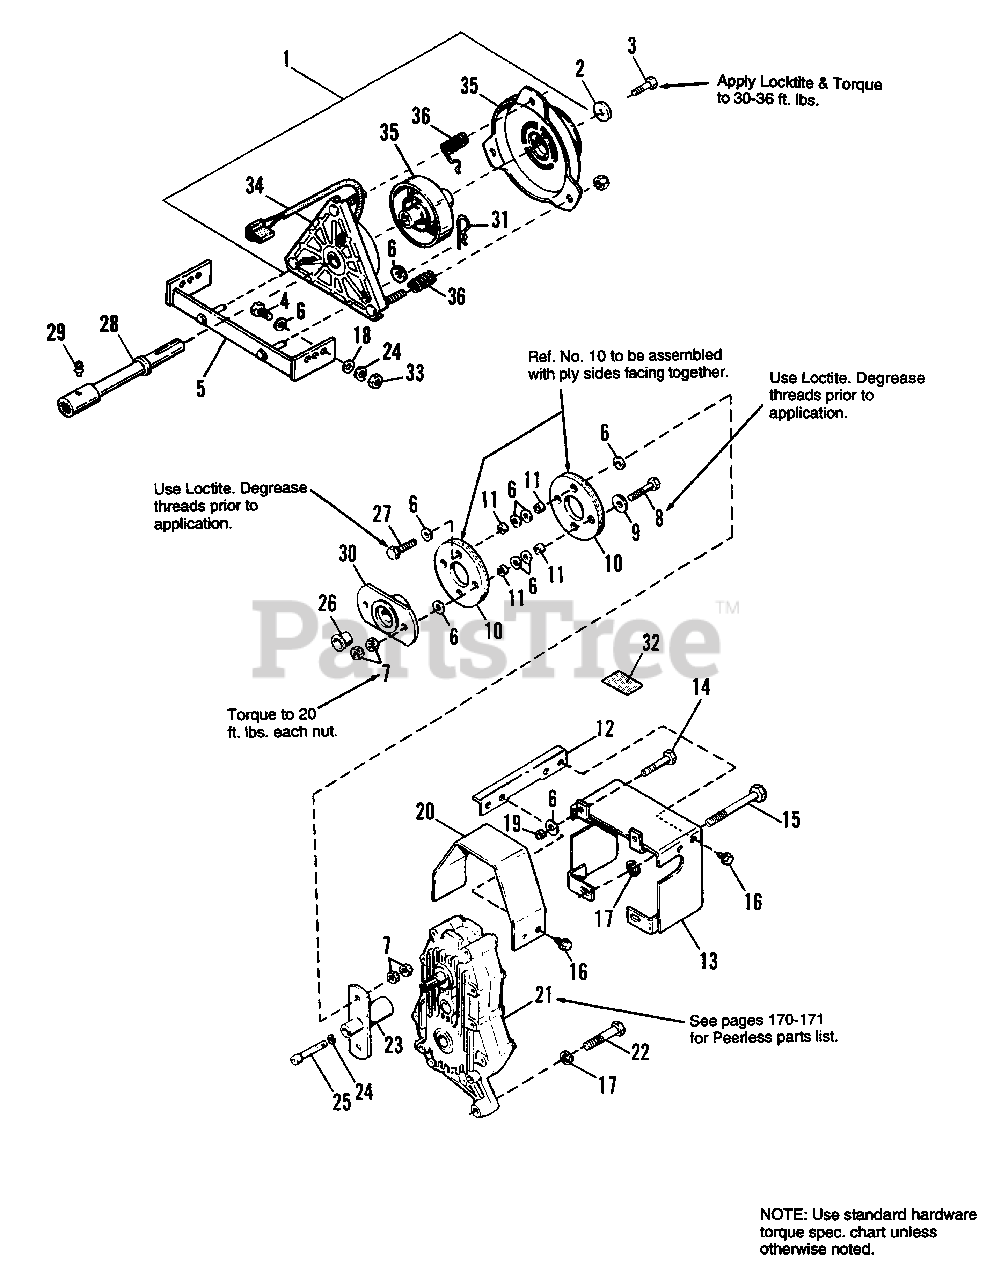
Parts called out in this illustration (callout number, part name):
1	CLUTCH, Electric
3	CAPSCREW, Hex Hd., 3/8-16 x 1, Gr. 5
4	CAPSCREW, Whizlock, 5/16-18 x 1
5	PLATE ASSY., Rear P.T.O.
6	WASHER, Plain, 11/32 I.D. X 3/4 O.D. X 1/16
7	NUT, Hex, Centerlock, 5/16-18
8	CAPSCREW, Hex Head 5/16-18 x 2 G5
9	WASHER, Plain, 5/16 x 1-1/2 x 9/64
10	COUPLING, Flex
12	SUPPORT, P.T.O. Guard
13	GUARD ASSY., P.T.O.
14	CAPSCREW, Hex Head 5/16-18 x 2 G5
15	CAPSCREW, Hex Hd., 1/2-13 x 4, Gr. 8
16	CAPSCREW, Washer Hd., Taptite, 5/16-18 x 1/2
17	LOCKWASHER, 1/2
18	WASHER, Plain, 11/32 x 1
20	GUARD, Disc.
21	GEAR BOX, 2000 RPM (Peerless)
22	CAPSCREW, Hex Socket Hd., 1/2-13 x 2-1/4, Gr. 8
23	ADAPTER ASSY.
24	LOCKWASHER, 5/16
25	CAPSCREW, Hex Hd, 5/16-24 x 2-1/4
27	CAPSCREW, Hex Hd., 5/16-18 x 1-1/2, Gr. 5
28	SHAFT ASSY.
29	FITTING, Grease w/Ball
31	CLIP, Hair Pin
32	DECAL, Rear P.T.O.
33	NUT, Hex Hd., 5/16-18
34	FIELD ASSY.
35	ROTOR, ARMATURE & BRAKE ASSY.
36	ACCESSORY KIT
